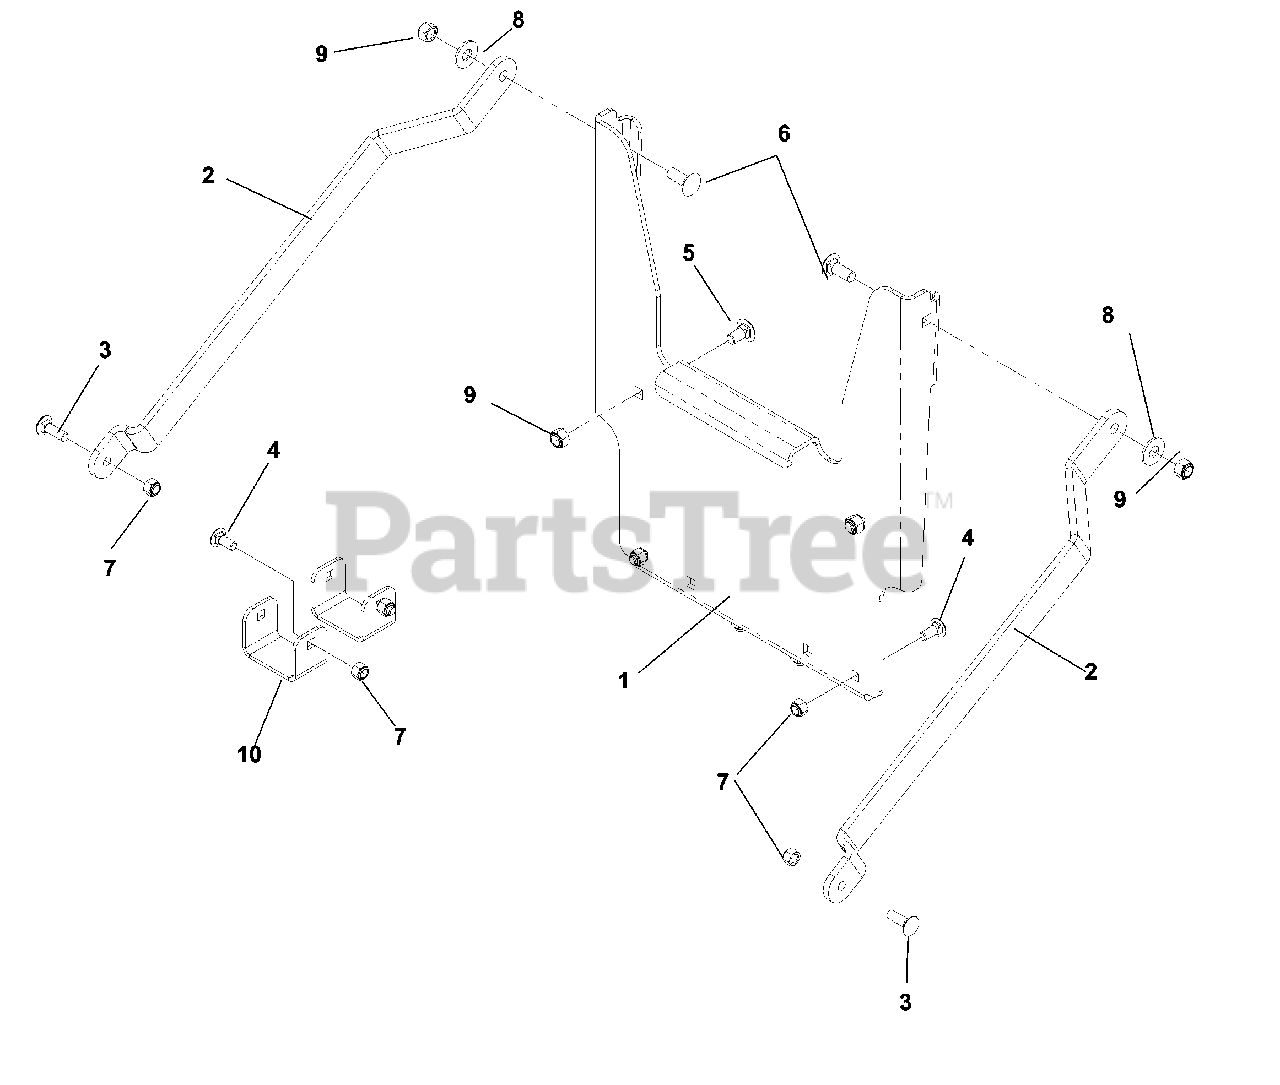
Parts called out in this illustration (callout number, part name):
1	PLATE, MOUNT, PAINTED
3	RHSNB 5/16C X 1
4	BOLT 5/16C X 3/4" CARRIAGE
5	RHSNB 3/8-16 X 3/4 GR5 ZD
6	RHSNB 3/8C X 1
7	NUT 5/16 NYLOC
8	WASHER 3/8 FLAT
9	NUT 3/8-16 NYLOC
10	EXTENSION, STRAP
